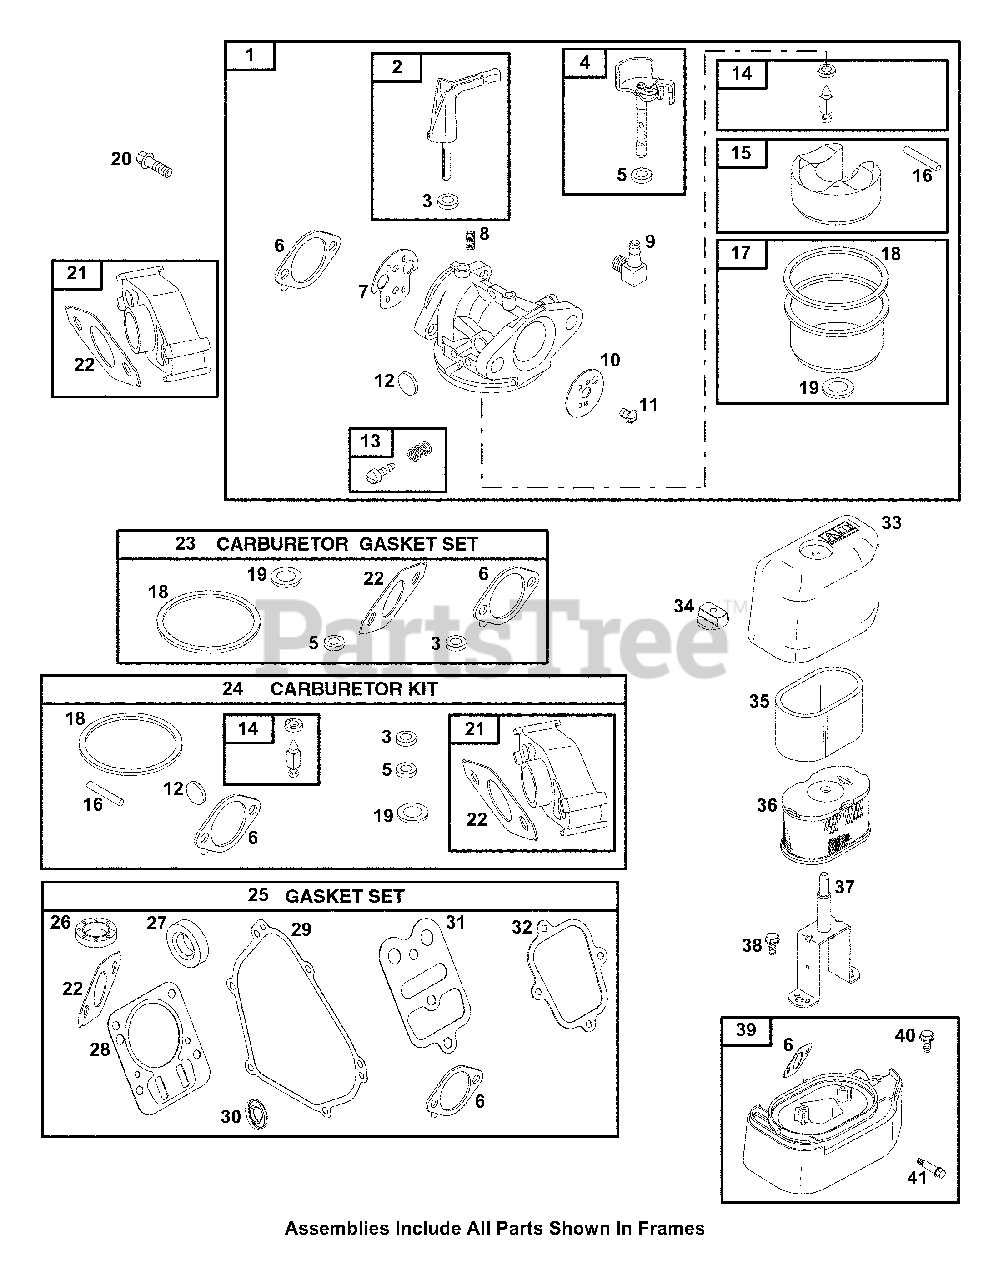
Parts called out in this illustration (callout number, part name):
1	Carburetor
2	Shaft-Choke
3	Washer (Choke Shaft Seal)
4	Shaft-Throttle
5	Washer (Throttle Shaft)
6	Gasket-Air Cleaner
7	Valve-Choke
8	Spring-Detent (Choke)
9	Connector-Hose
10	Valve-Throttle
11	Screw (Throttle Valve)
12	Plug-Welch
13	Kit-Idle Speed
14	Valve-Needle
15	Float-Carburetor
16	Pin-Float Hinge
17	Bowl-Float
18	Gasket-Float Bowl
19	Washer-Seal
20	Screw (Carburetor)
21	Spacer-Carburetor
22	Gasket-Intake
23	Gasket Set-Carburetor
24	Carburetor Kit
25	Gasket Set
26	Seal-Oil
28	Cylinder Head Gasket
29	Gasket-Crankcase
30	Seal-Valve
31	Gasket-Plate
32	Gasket-Rocker Cover
33	Cover-Air Cleaner
34	Knob-Air Cleaner
35	Filter-Air (Pre-Filter)
36	Filter A/C Cartridge
37	Air Cleaner Bracket
38	Screw (Air Cleaner Bracket)
39	Base-Air Cleaner
40	Screw (Air Cleaner Base)
41	Screw (Air Cleaner Base)
